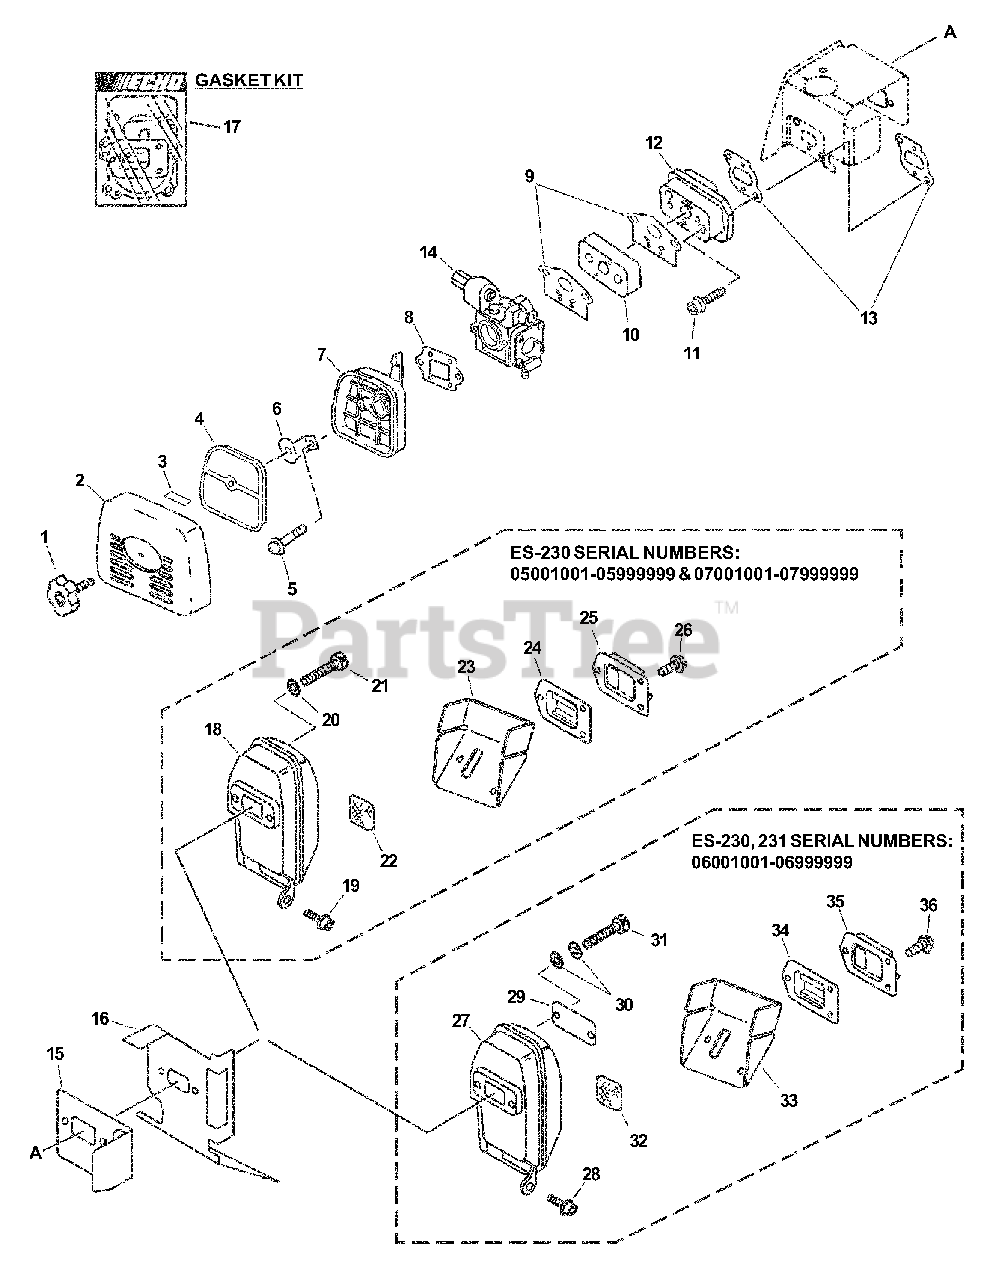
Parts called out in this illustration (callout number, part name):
1	THUMBSCREW
2	COVER, AIR FILTER
3	LABEL, CHOKE
4	FILTER, HEAVY-DUTY AIR
5	SCREW 5×65
6	PLATE, PREVENT
7	CASE, AIR FILTER
9	GASKET, CARBURETOR
10	INSULATOR, INTAKE
11	BOLT 5×25
12	INSULATOR, INTAKE
13	GASKET, INTAKE
14	CARBURETOR
15	GASKET, EXHAUST
16	HEAT SHIELD, EXHAUST
17	GASKET KIT
18	MUFFLER
19	BOLT 5×16
20	WASHER, FLAT 5.5×10×0.8
21	BOLT 5×60
22	SCREEN, SPARK ARRESTER
23	GASKET, EXHAUST
24	GUIDE, EXHAUST - INNER
25	GUIDE, EXHAUST
26	SCREW 4×10
27	MUFFLER
28	BOLT 5×16
29	PLATE, EYE
30	CONICAL WASHER
31	BOLT M5×65
32	SCREEN, SPARK ARRESTER
33	GASKET, EXHAUST
34	GUIDE, EXHAUST
35	GUIDE, EXHAUST
36	SCREW 4×12
